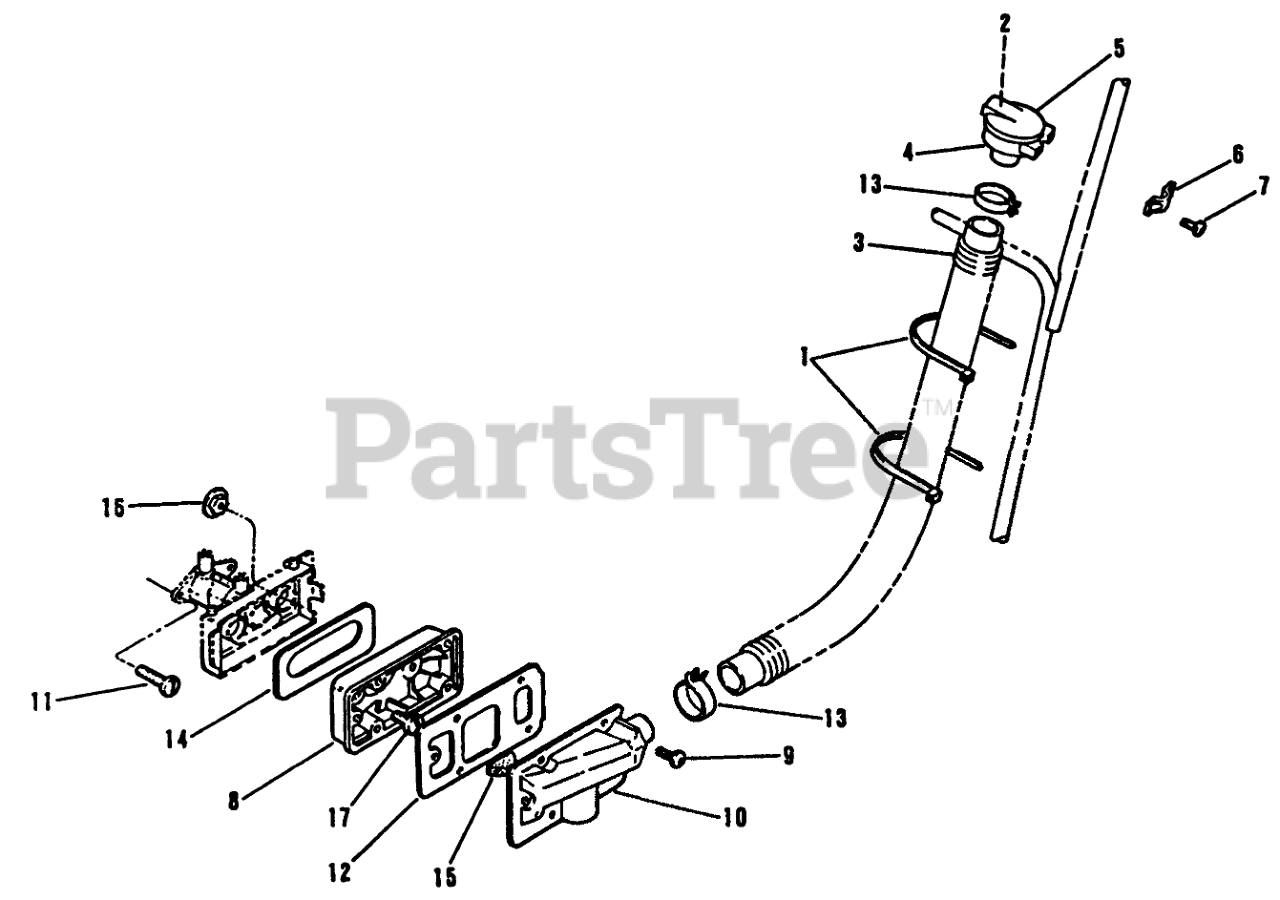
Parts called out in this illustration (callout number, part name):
1	Tie Strap
2	AIR FIL.ELEM S
3	HOSE-REMOTE FILTER
4	CHAMBER-AIR FILTER
5	CAP-AIR FILTER
6	CLAMP-AIR FILTER
7	Screw
8	INSERT - CHAMBER
9	SCREW S
10	COVER - INSERT
11	SCREW
12	GASKET - COVER
13	CLAMP
14	GASKET - CHAMBER
15	ELEMENT-FILTER
16	LOCK NUT
17	Screw
